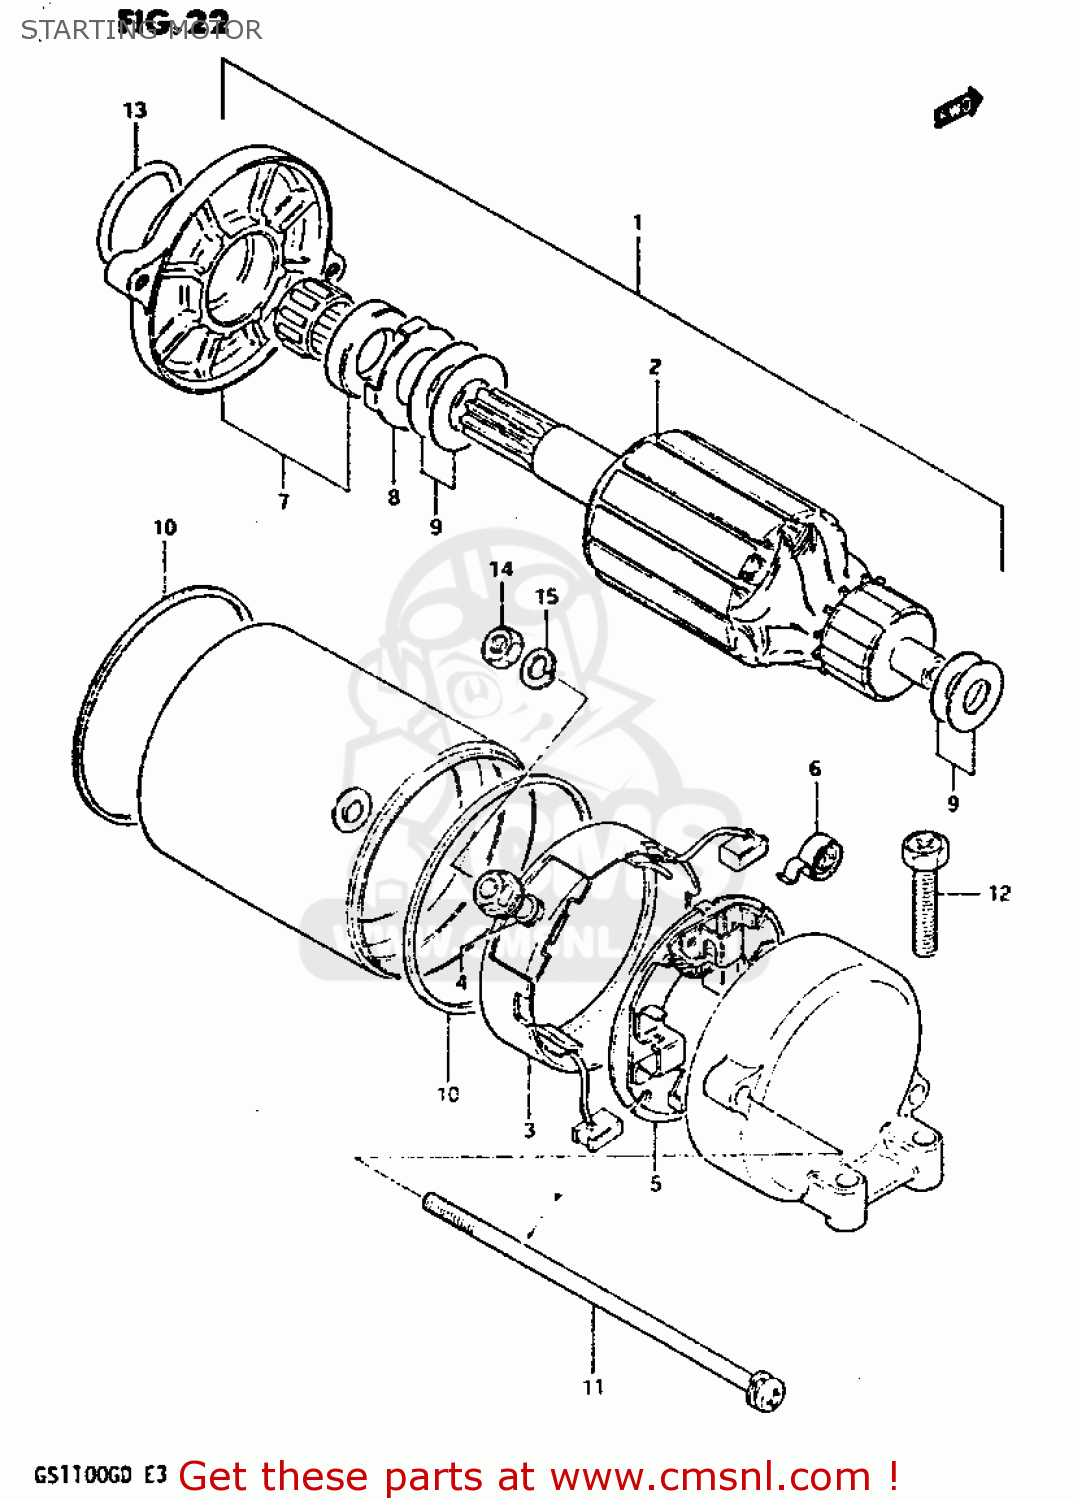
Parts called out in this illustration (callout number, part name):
1	MOTOR ASSY,STARTING
2	ARMATURE
3	BRUSH TERMINAL SET
4	O RING
5	HOLDER,BRUSH
6	SPRING,BRUSH
7	HOUSING SET,STARTING MOTOR
8	SHIM SET
9	SHIM SET
10	SEAL,RING
11	BOLT,STARTING MOTOR HOUSING
12	SCREW (6X25)
13	O RING(D:3,ID:24.5)
14	NUT 6MM
15	WASHER,LOCK
